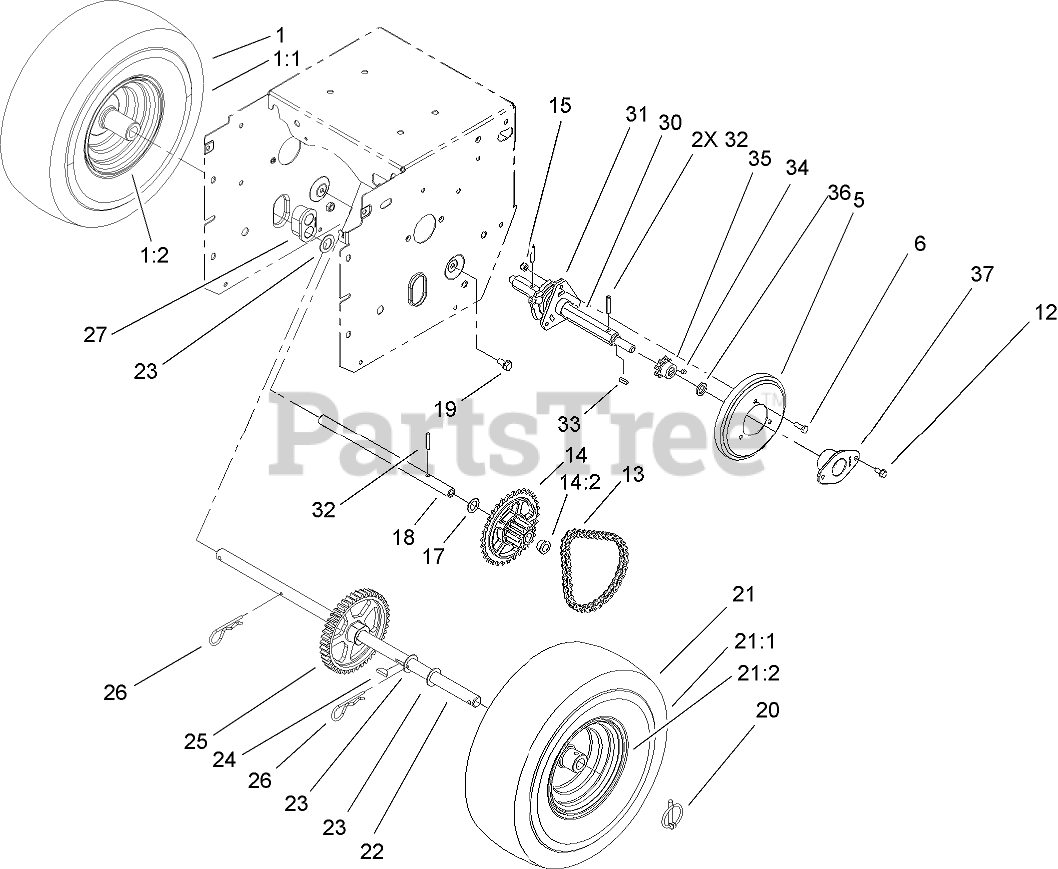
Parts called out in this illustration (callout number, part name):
1	RH WHEEL AND TIRE ASM
1:2	RIM-TIRE
5	WHEEL-FRICTION
6	SCREW-HH
12	SCREW-HWH
13	CHAIN-ROLLER
13	LINK-CONNECTING
14	SPROCKET ASM
14:2	BUSHING-FLANGE
15	NUT-LOCK, NI
17	WASHER-FLAT
18	SHAFT-INTERMEDIATE
19	SCREW-HWHTF
20	KLIK PIN ASM
21	LH WHEEL AND TIRE ASM
21:2	RIM-TIRE
22	SHAFT-AXLE
23	WASHER-THRUST
24	KEY-WOODRUFF
25	GEAR-AXLE, 44 TOOTH
26	PIN-HAIR
27	BEARING-AXLE
30	SHAFT-HEX
31	TRUNNION-HEX
32	PIN-ROLL, SLOTTED
33	KEY-SQUARE
34	SCREW-HSH
35	SPROCKET-8 TOOTH
36	SPACER-BUSHING
37	RETAINER-BEARING
